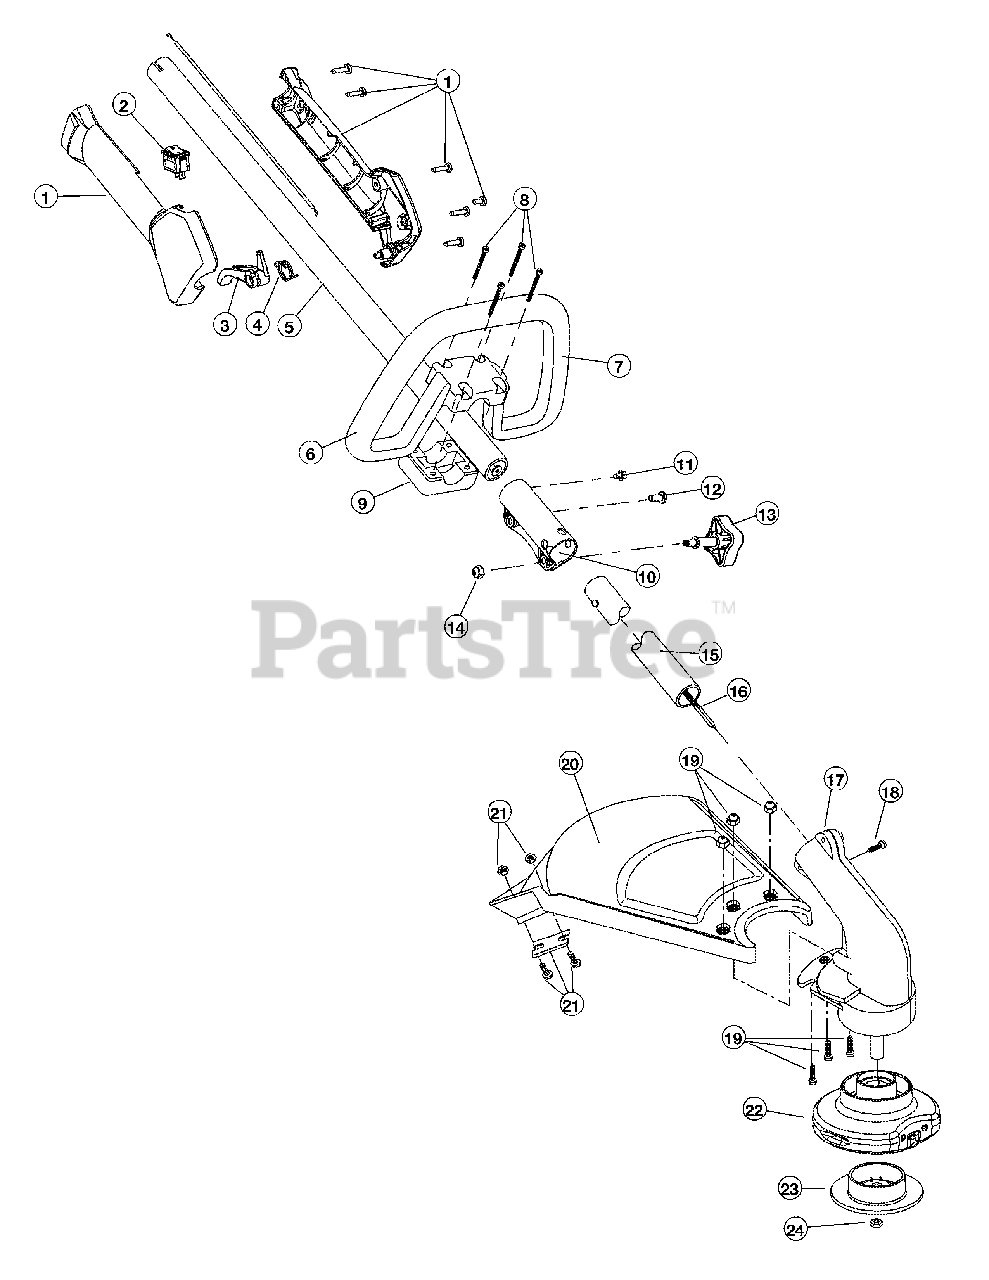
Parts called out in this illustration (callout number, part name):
1	Throttle Housing Assembly (Incl. 2-4)
3	Throttle Trigger
4	Throttle Trigger Spring
5	Upper Drive Shaft Housing Assembly
6	Deluxe D-Handle Assembly (Incl. 7-9)
7	Deluxe D-Handle
9	Deluxe D-Handle Base
10	Split Boom Coupler (Incl. 11-14)
13	Adjustment Knob (Incl. 14)
14	Knob Retaining Nut
15	Lower Drive Shaft Housing Assembly
16	Lower Flexible Drive Shaft
17	Gearbox Assembly
18	Anti-Rotation Screw
19	Shield Mounting Hardware
20	Shield Assembly (Incl. 21)
21	Blade Assembly
22	Fixed Line Head Assembly (Incl. 23 & 24)
23	Glide Cap
24	Locknut
